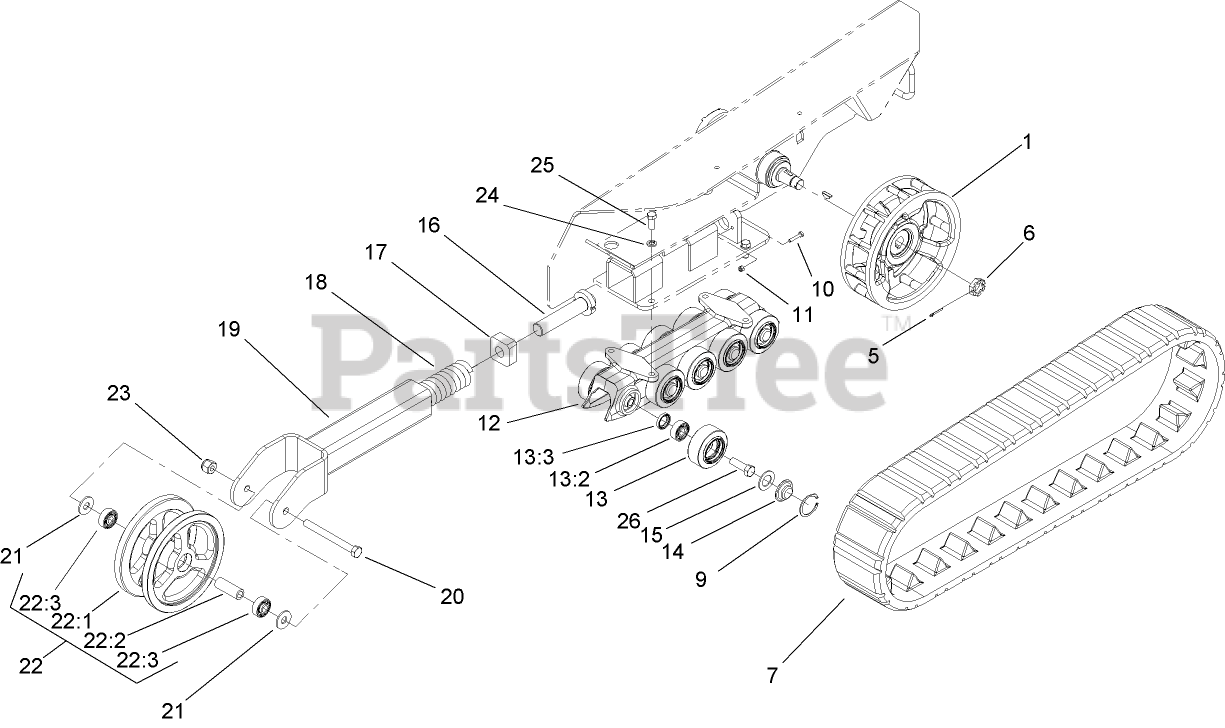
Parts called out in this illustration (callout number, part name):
1	WHEEL-DRIVE
5	PIN-COTTER
7	TRACK
9	RING-SNAP, INTERNAL
10	SCREW-HH
11	NUT-LOCK, NI
12	GUIDE-TRACK
13	Road Wheel ASM
13:2	BEARING
13:3	SEAL-OIL
14	CAP-WHEEL, BEARING
15	Gasket-Bogie
16	BOLT-TENSIONER
17	BLOCK-TENSIONER
18	SPRING-COMPRESSION
19	TENSIONER ARM ASM
20	SCREW-HH
21	WASHER-FLAT
22	TENSIONER WHEEL ASM
22:1	WHEEL-TENSIONER
22:2	SPACER-WHEEL, TENSIONER
22:3	BEARING
23	NUT-HEX
24	WASHER-LOCK
25	SCREW-HH
26	SCREW-HH
